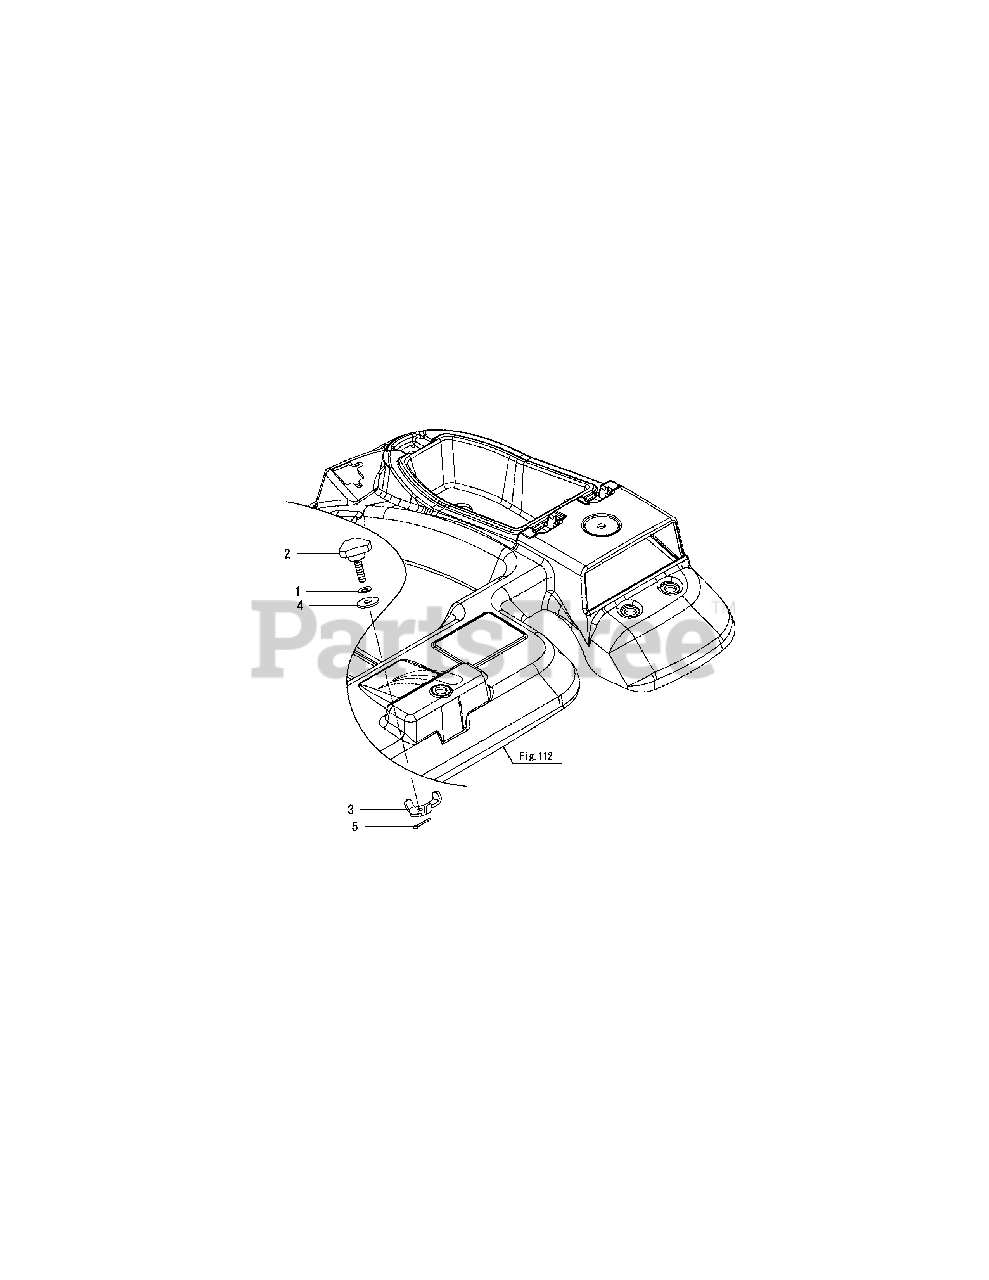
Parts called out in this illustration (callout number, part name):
1	SPRING, CONICAL
2	KNOB, HYD.CONTROL
3	STOPPER, HYD.CONTROL
5	COTTER PIN 2.0X16
